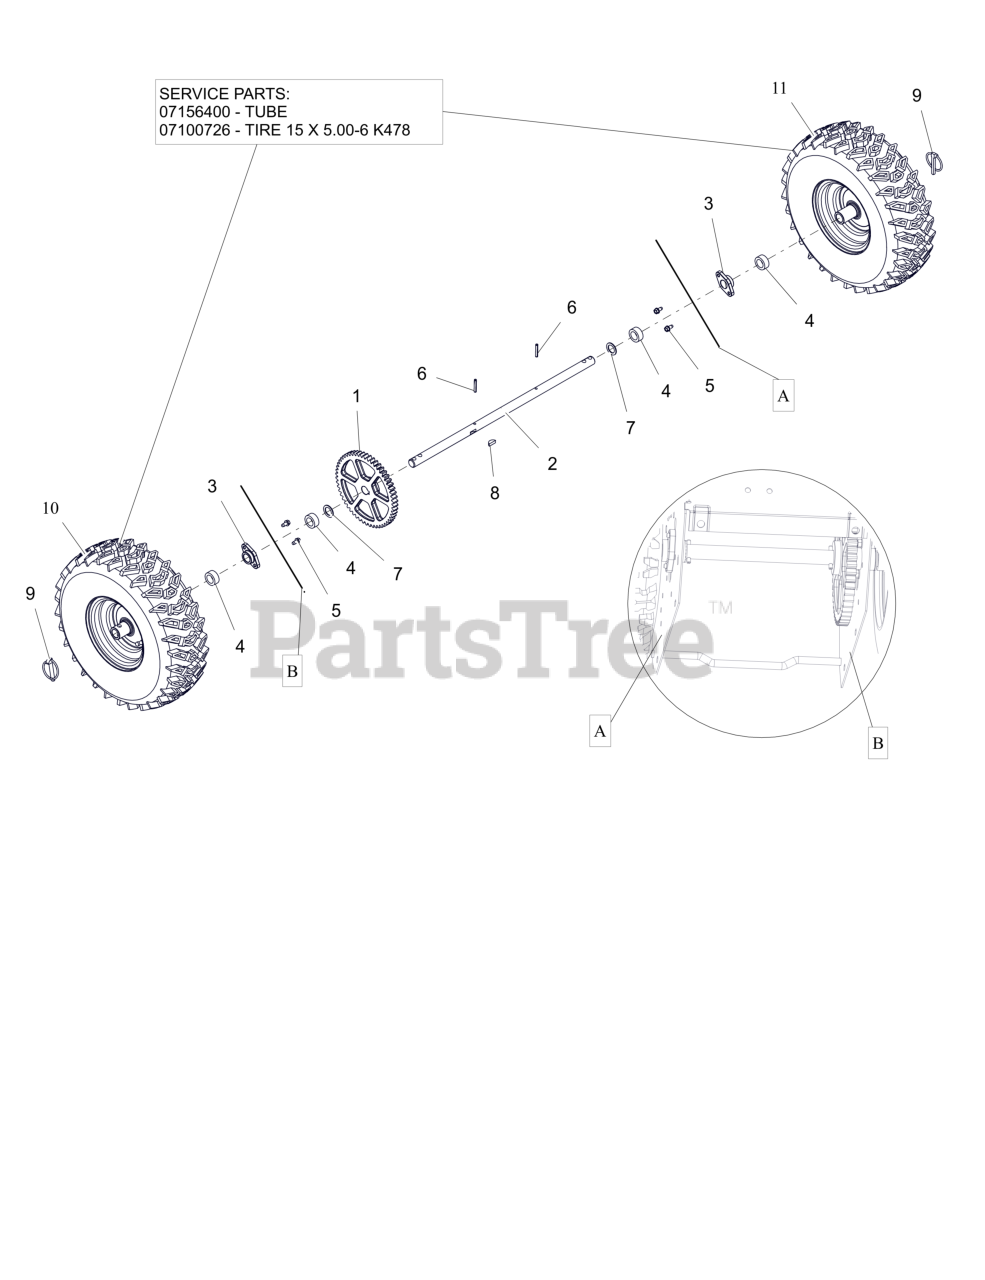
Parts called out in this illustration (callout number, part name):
1	SPUR GEAR, 54T .75ID X 6.75PD
2	AXLE, COMPACT
3	BSHG .75X1.125X.65
4	BSHG-SLV .766 X 1.125 X .500
5	SCR-TAP .25-20X.50 HWH ZCC
6	PIN-ROLL .188X1.25
7	WSHR, FLT .754X1.125X.062 ZCC
8	KEY-WDRF .25X.750X.313 SAE91
9	PIN-LOK .31X1.75
10	TIRE/WHEEL, RH 15X5-6 PIN T2
10	TUBE 15 X 5.00-6
10	TIRE, 15X5.00-6 K478
11	TIRE/WHEEL LH 15X5.00-6 PIN T2
11	TUBE 15 X 5.00-6
11	TIRE, 15X5.00-6 K478
